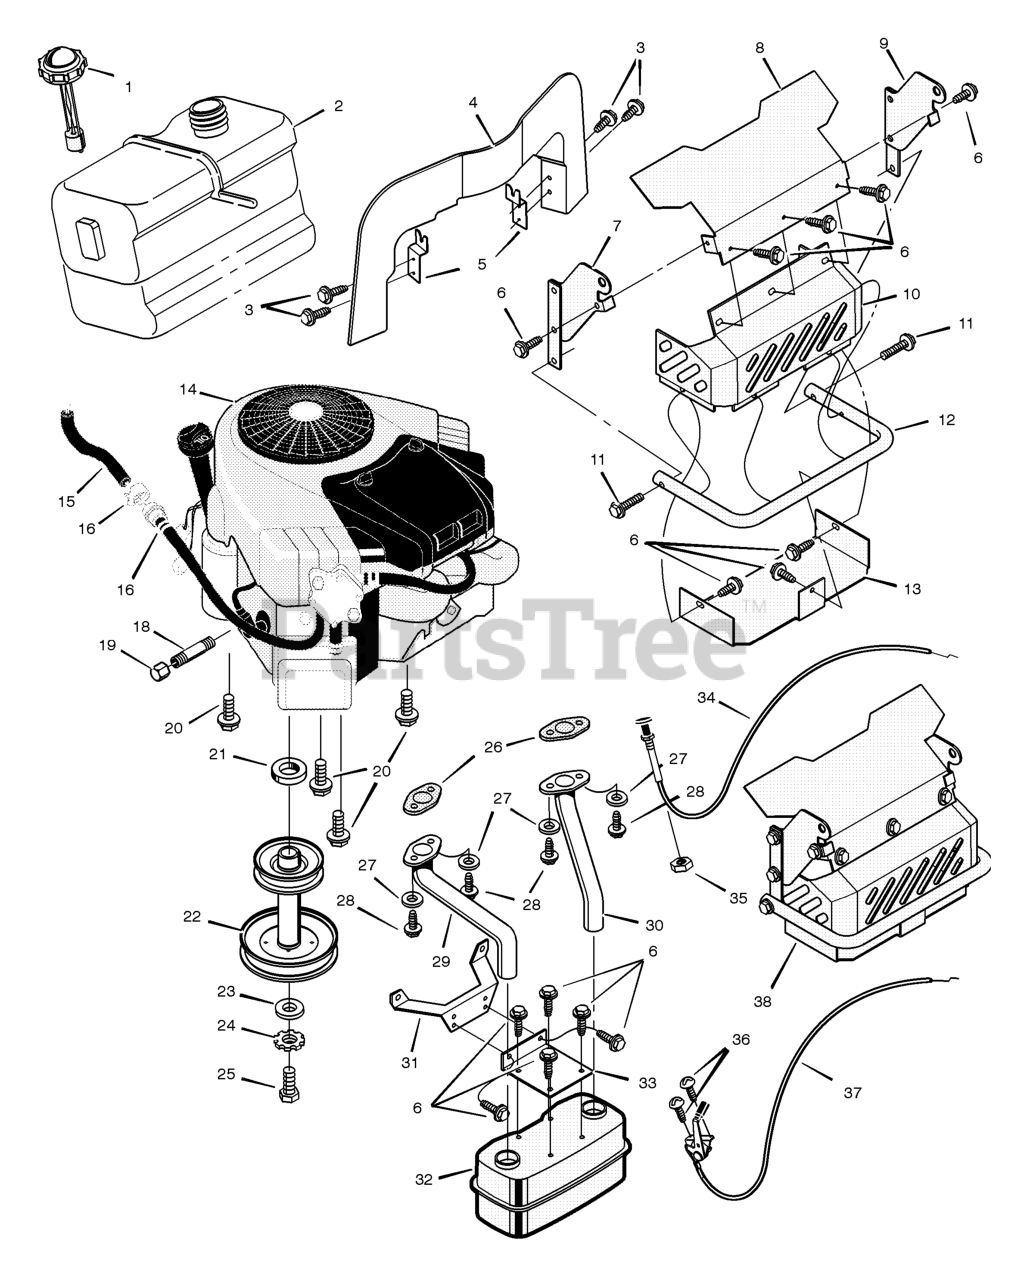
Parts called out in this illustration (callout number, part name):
1	Cap, Fuel
2	Tank, Fuel
3	Screw
4	Baffle
5	Clip, Baffle Mounting
7	Assembly, Right Grille Support
8	Shield, Heat
9	Assembly, Left Grille Support
10	Shield, Heat
13	Shield, Lower
14	Engine *
15	Fuel Line (Must cut to length)
16	Clamp
18	Pipe, Oil Drain
19	Cap, Oil Drain
20	Bolt
22	Pulley, Stack
24	Lockwasher
27	Washer
28	Bolt
29	Tube, Right Exhaust
30	Tube, Left Exhaust
31	Bracket, Muffler Mount
32	Muffler
33	Bracket, Muffler
35	Nut
37	Control, Throttle
38	Shield Assembly, Heat
